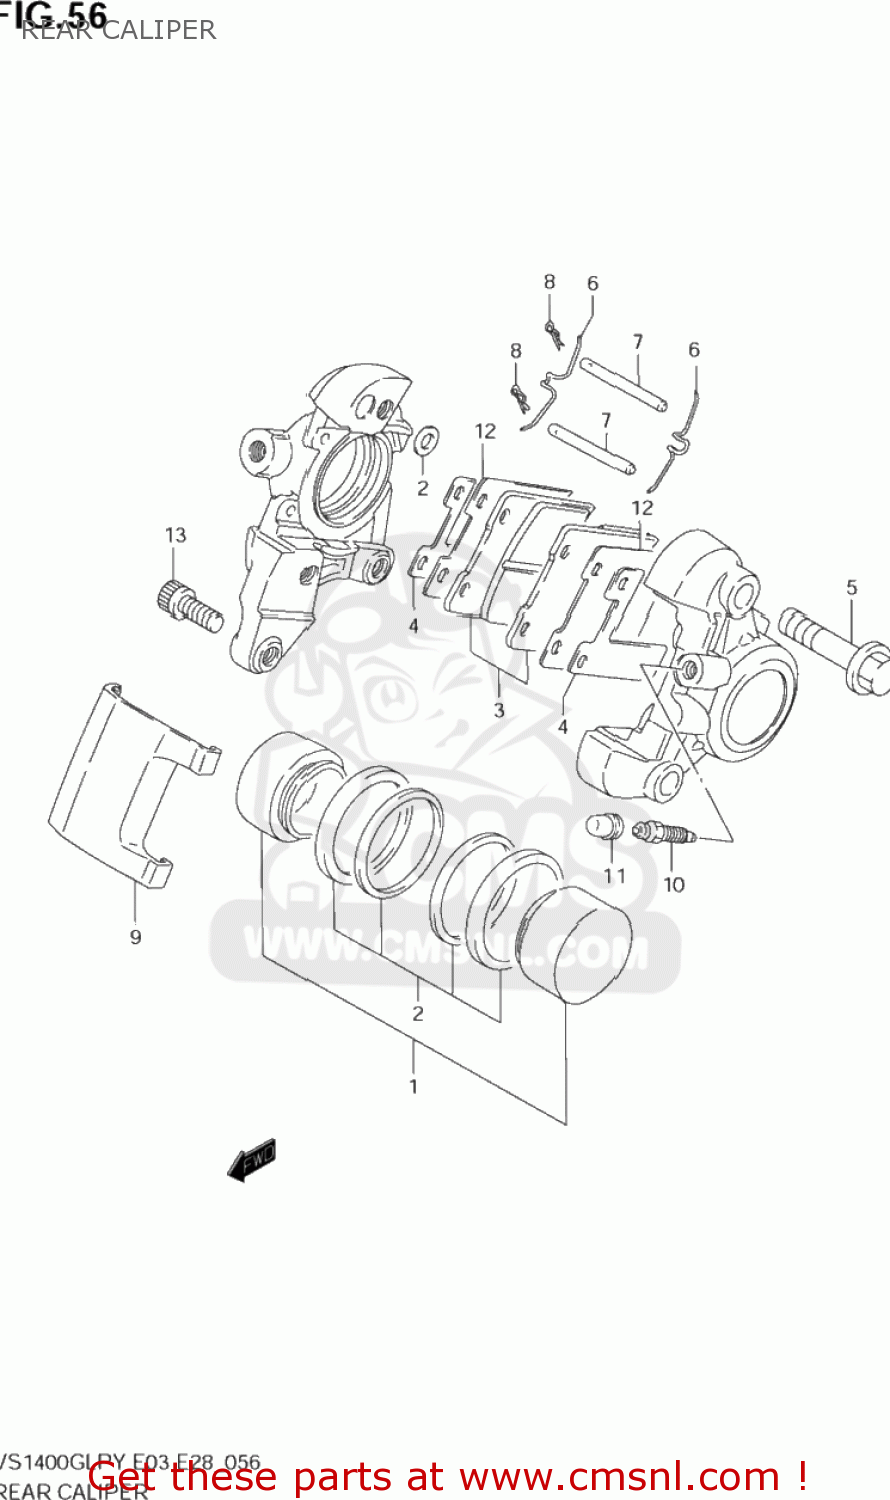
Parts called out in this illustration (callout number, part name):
1	PISTON SET
2	SEAL SET,PISTON
3	PAD SET (NAS)
4	SHIM
5	BOLT,HOUSING
6	SPRING
7	PIN,PAD
8	CLIP,PAD PIN
9	COVER
10	BLEEDER
11	CAP,BLEEDER PLUG
12	SHIM,PAD
13	BOLT
